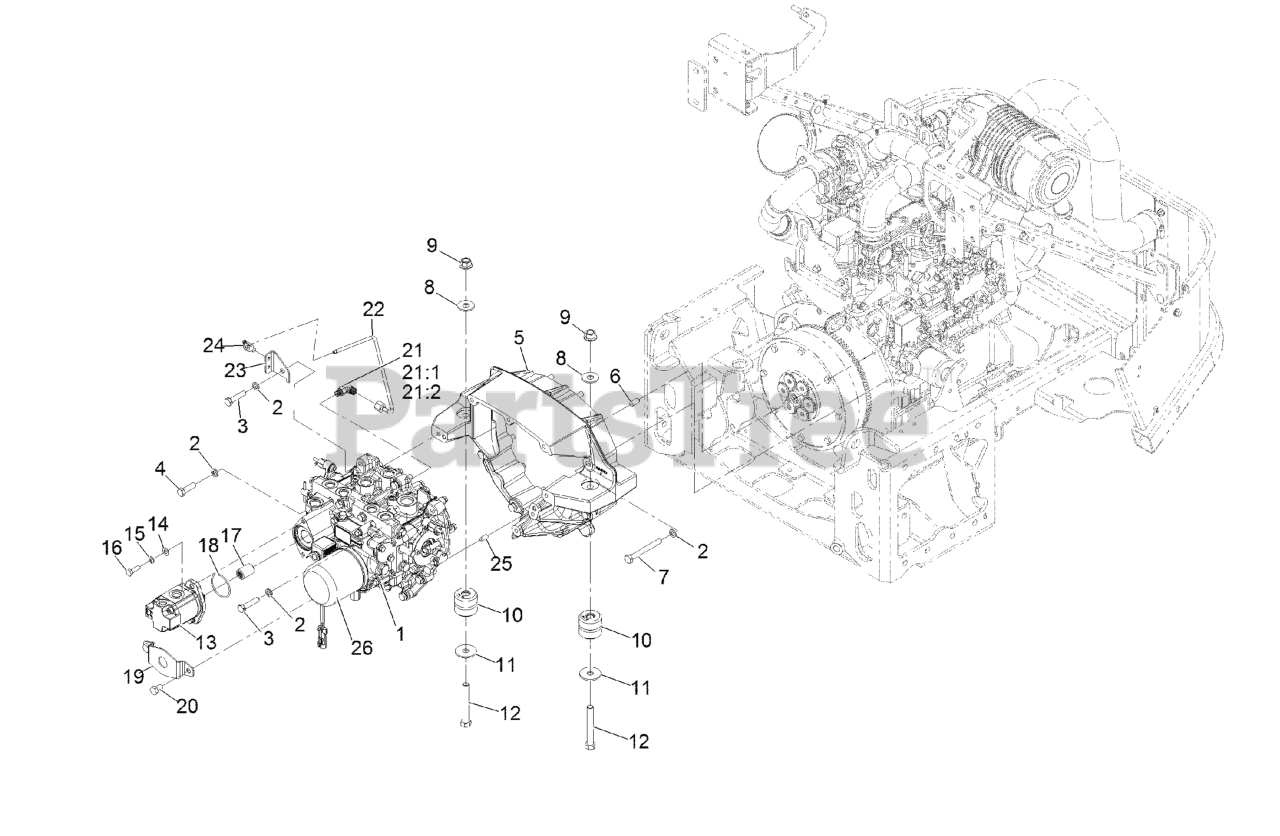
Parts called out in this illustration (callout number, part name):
1	TRANSMISSON ASM
2	WASHER-LOCK
3	SCREW-HH
4	SCREW-HH
5	Housing-Flywheel
6	PIN-DOWEL
7	SCREW-HH
8	WASHER-FLAT
9	Nut-Lock 1/2-13
10	MOUNT-ISOLATOR
11	WASHER-THRUST
12	SCREW-HH
13	HYD GEAR PUMP ASM
14	WASHER-PLAIN
15	WASHER-LOCK
16	SCREW-HH
17	COUPLER-SPLINE
19	SHIELD-SEAL
20	SCREW-HH
21	FITTING-ELBOW, 90 DEG
21:1	O-RING
21:2	O-RING
22	TUBE ASM
23	SUPPORT-TUBE
24	CLIP-TIE
25	PIN-DOWEL
26	FILTER-OIL, HYD
